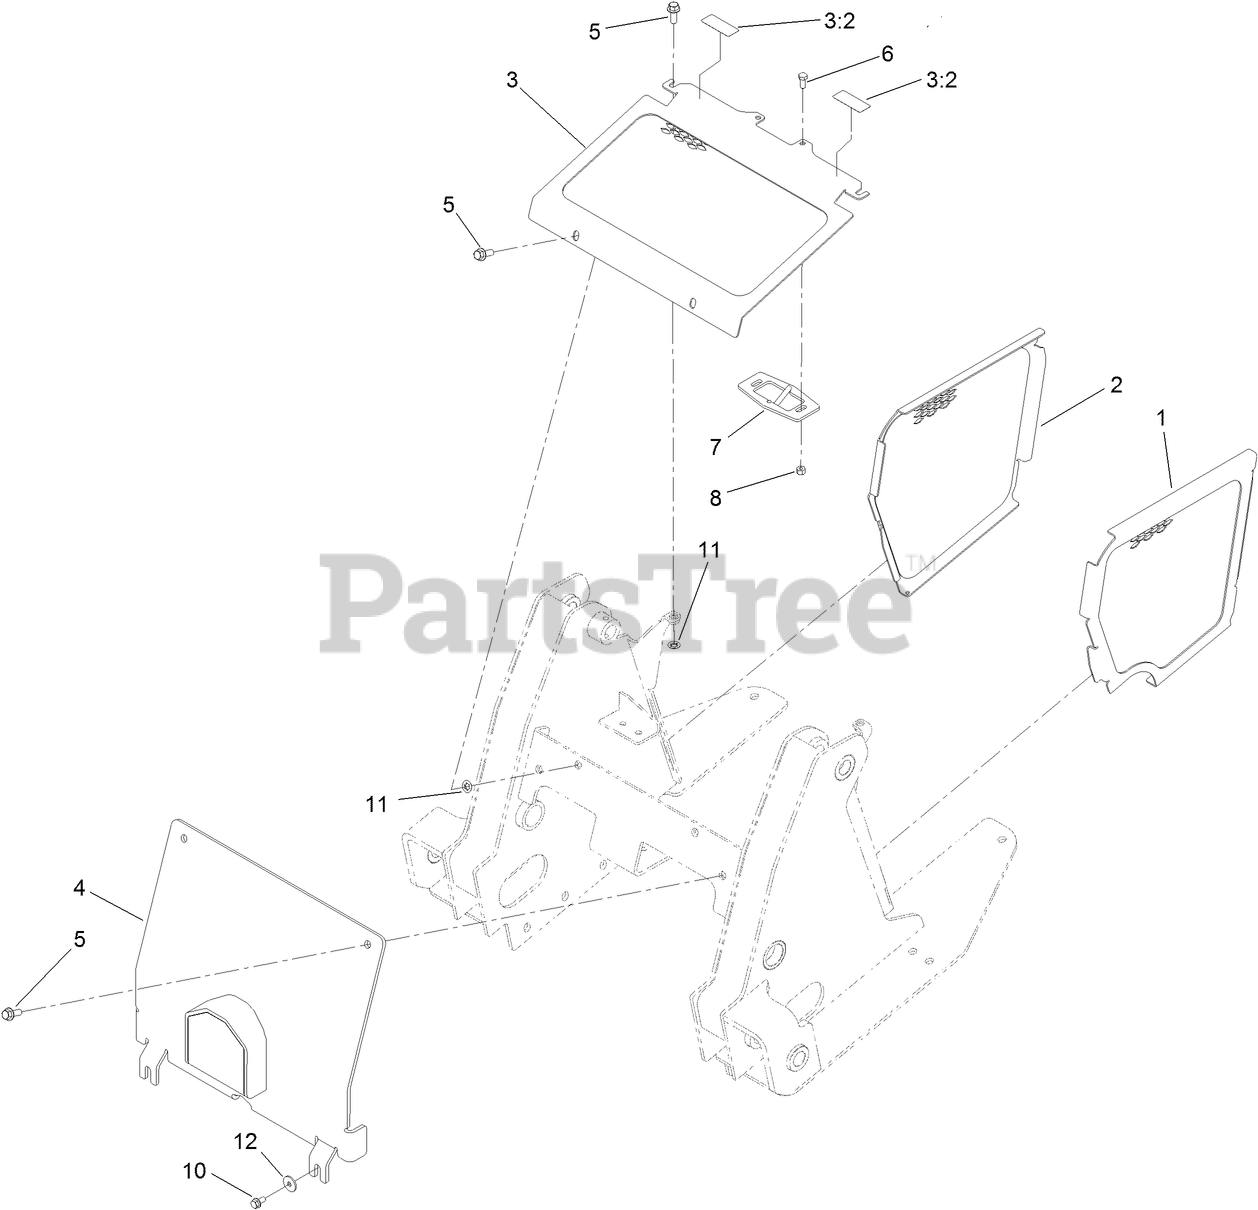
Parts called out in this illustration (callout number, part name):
1	PANEL-SIDE, LH
2	PANEL-SIDE, RH
3	FRONT COVER ASM
3:2	DECAL-SURFACE, HOT
4	COVER-FRONT
5	SCREW-HHF
6	SCREW-HH
7	HOOD LATCH/ROD ASM
8	NUT-LOCK, NI
10	SCREW-HHF
11	NUT-PUSH
12	WASHER-FLAT
